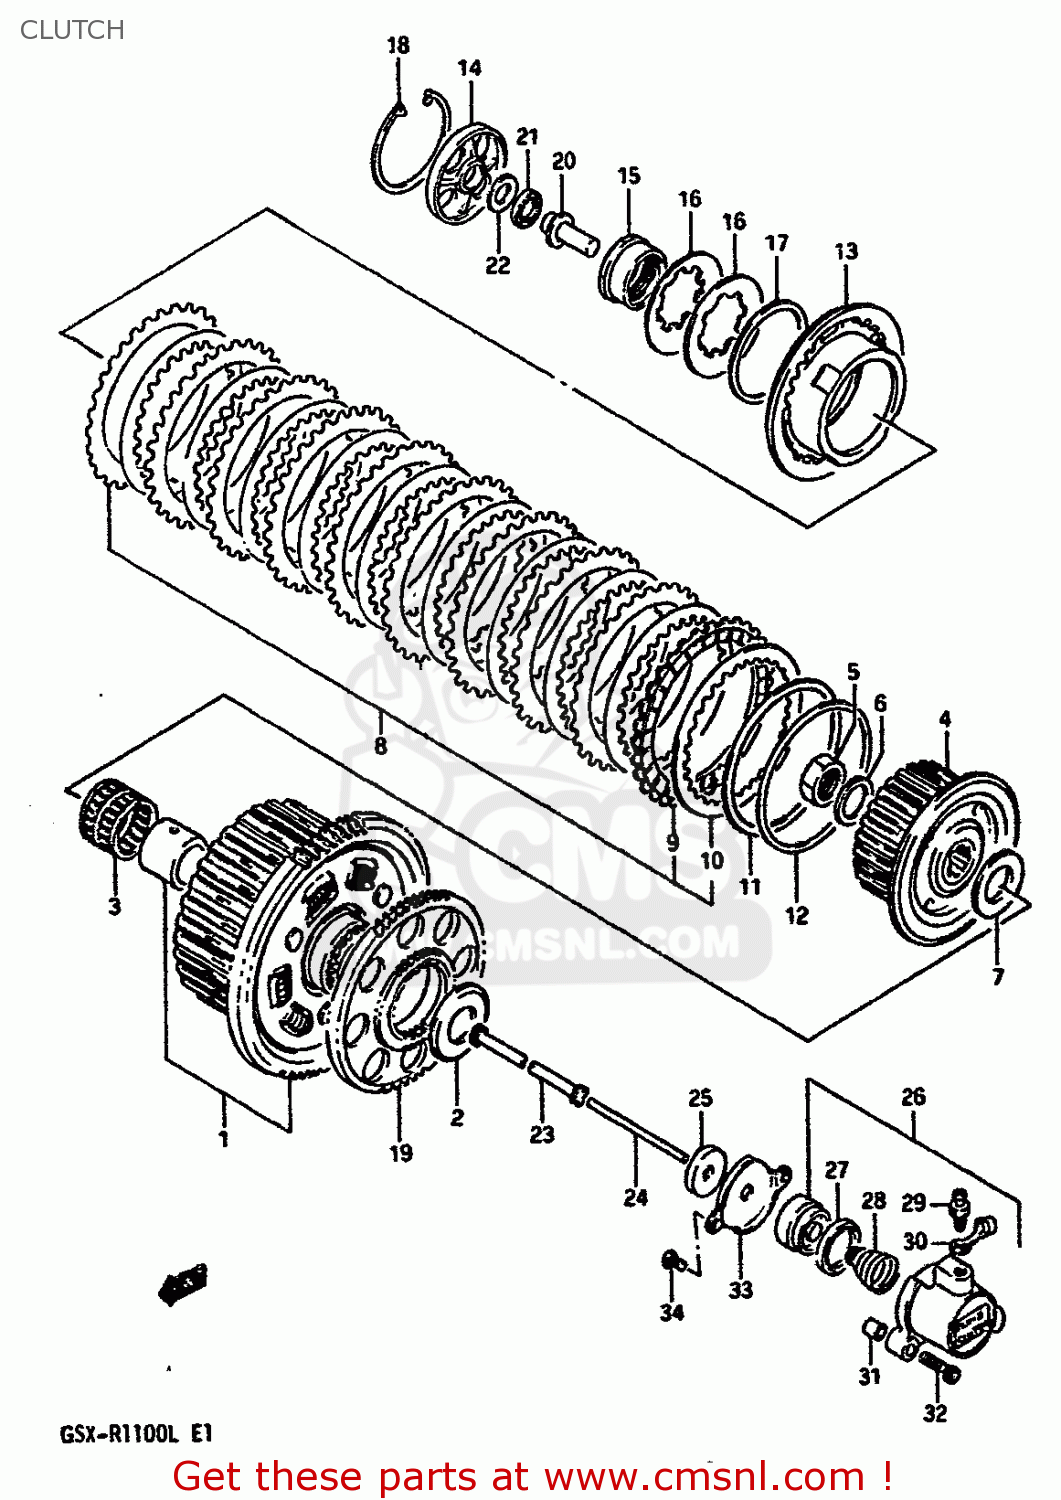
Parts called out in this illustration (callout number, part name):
1	GEAR ASSEMBLY,PRIMARY DRIVE
2	WASHER(25X54X2.5)
3	BEARING(35X40X35.8)
4	HUB,CLUTCH SLEEVE
5	NUT
6	WASHER
7	WASHER(25X50X2.5)
8	PLATE ASSEMBLY,CLUTCH
9	PLATE,CLUTCH DRIVE NO.1 (NAS)
10	PLATE,CLUTCH DRIVEN (NAS)
11	WASHER
12	SEAT,CL SLEEVE HUB WAVE WASHER
13	DISC,CLUTCH PRESSURE
14	LIFTER,CLUTCH PRESSURE DISC
15	HOLDER,CLUTCH SPRING
16	WASHER
17	SEAT,CLUTCH SPRING
18	CIRCLIP
19	GEAR,GENERATOR DRIVE
20	PIECE,CLUTCH PUSH
21	BEARING(15X28X2)
22	WASHER
23	ROD,CLUTCH
24	ROD,CLUTCH PUSH
25	SEAL,OIL(6X34X5.5)
26	CYLINDER,CLUTCH RELEASE
27	CUP
28	SPRING,CLUTCH CYLINDER
29	BLEEDER
30	CAP,BLEEDER
31	PIN
32	BOLT
33	PLATE,CLUTCH PUSH ROD
34	SCREW
